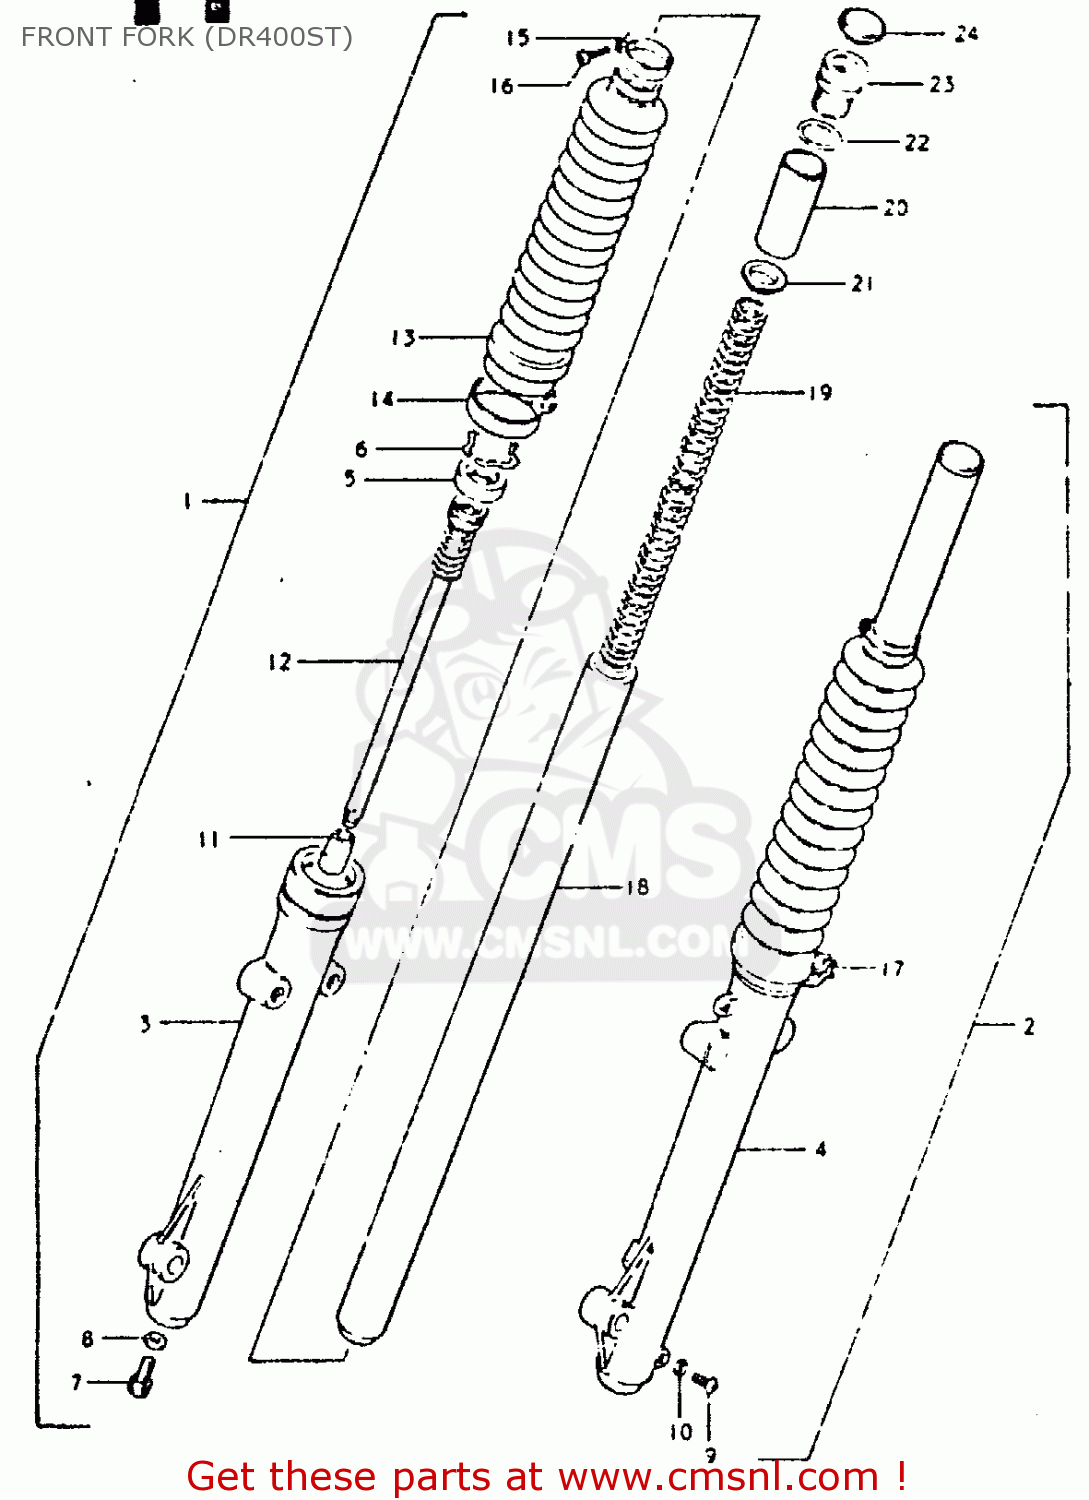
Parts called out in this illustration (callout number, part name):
1	DAMPER ASSY, RH
2	DAMPER ASSY, LH
3	TUBE,OUTER,RIGHT
4	OUTER TUBE, LH
5	OIL SEAL,FRONT FORK
6	7
7	BOLT,FORK CYLINDER(10X25)
8	GASKET (NAS)
9	SCREW
10	GASKET,DRAIN,PLUG (NAS)
11	PIECE,OIL LOCK
12	CYLINDER,FRONT FORK
13	BOOT
14	BAND,FRONT FORK COVER
15	BAND,BOOT
16	SCREW
17	BAND,FORK COVER BOOT
18	INNER TUBE
19	SPRING
20	SPACER,SPRING
21	GUIDE,FRONT FORK SPRING C
22	O RING
23	CAP,FORK INNER TUBE
24	CAP,FRONT FORK
